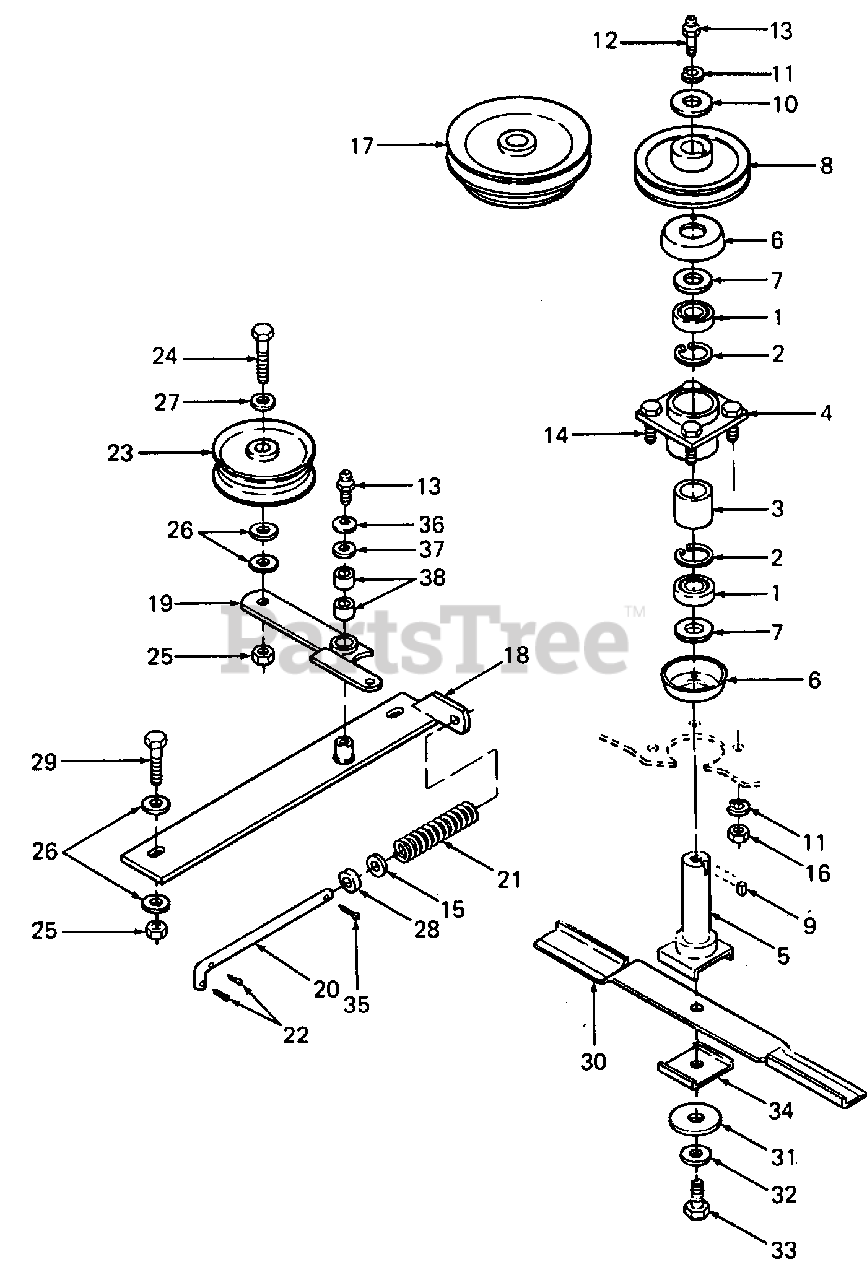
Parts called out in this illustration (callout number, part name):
1	Bearing
2	Ring, Internal Snap
3	Spacer, Bearing
4	Housing, Spindle w/o Bolts
5	Shaft, Spindle
6	Cup, Bearing
7	Washer
8	Pulley, Outer
9	Key, 1/4 X 1 Sq Parallel
11	Washer, Lock, 1/2
12	Bolt Assy
13	Fitting, Grease
14	Bolt, 1/2-13 Full Thread Rd Hd
15	Washer, Flat, .531 ID X 1.062 OD X .074 Thk
16	Nut, Hex, 1/2-13
17	Pulley, Center
18	Plate, Idler
19	Arm, Idler
20	Rod, Idler Spring
21	Spring, Idler
22	Pin, Cotter, 1/8 Dia X 1.25 Lg
23	Pulley, Idler
24	Screw, Hex Cap, 3/8-16 X 1.75 Lg GR5
25	Nut, Hex Center Lock, 3/8-16
26	Washer, Flat, .438 ID X 1.00 OD X .064 Thk
27	Washer, Lock, 3/8
29	Screw, Hex Cap, 3/8-16 X 1.00 Lg GR5
30	Blade, Mower, 21.00 Lg
31	Washer, Mower Blade
32	Washer, Spring
33	Screw, Hex Cap, 1/2-20 X 1.5 Lg GR5
34	Retainer, Blade
35	Pin, Quick Attach
36	Washer, Spring
37	Washer, Flat, .438 ID X 1.00 OD X .064 Thk
38	Bushing, Oilite
